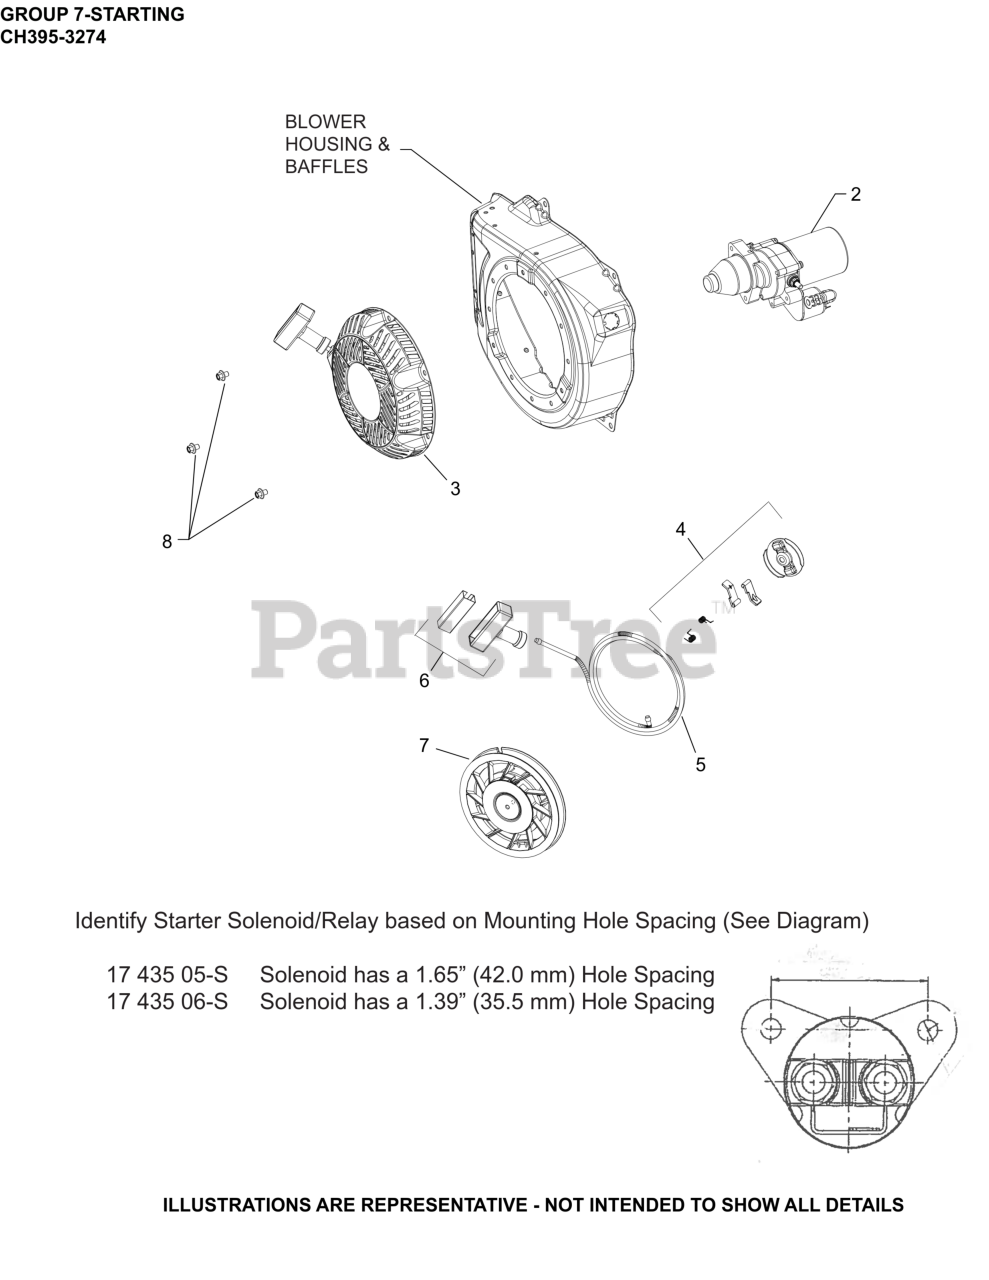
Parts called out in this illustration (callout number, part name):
2	STARTER ASSEMBLY
3	RETRACTABLE STARTER ASSEMBLY
4	KIT, PAWL REPAIR
5	KIT, ROPE
6	KIT, HANDLE
7	PULLEY, RECOIL
8	SCREW, M6 X 8 HEX FLANGE HEAD
